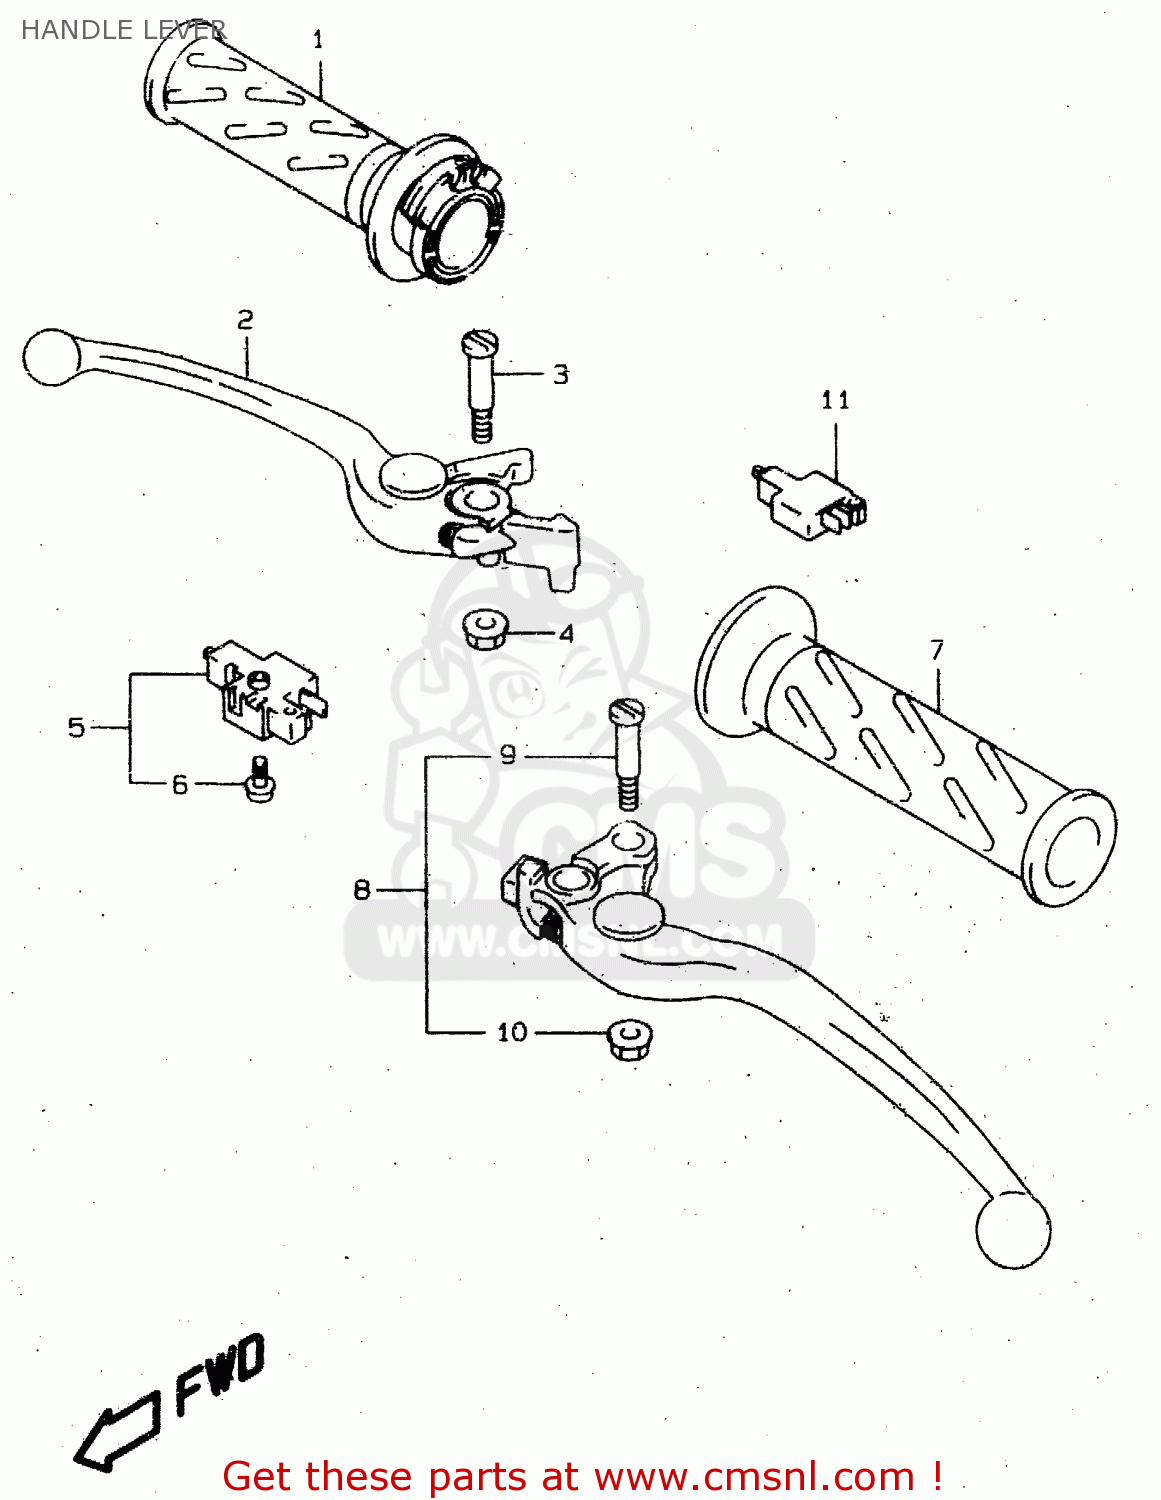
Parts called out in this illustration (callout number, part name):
1	GRIP,THROTTLE
2	LEVER ASSEMBLY,ADJUST
3	BOLT,LEVER PIVOT
4	NUT
5	SWITCH ASSEMBLY,STOP
6	SCREW
7	GRIP,LEFT
8	LEVER ASSY,CLUTCH
9	BOLT,LEVER PIVOT
10	NUT
11	SWITCH ASSY,CLUTCH
